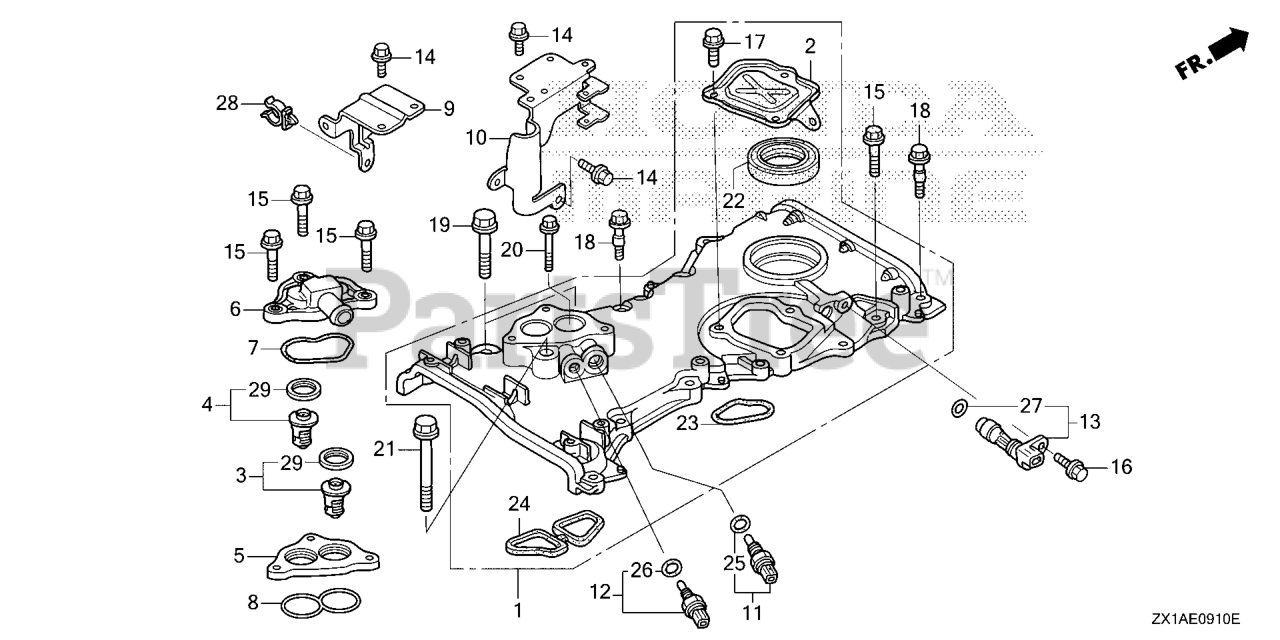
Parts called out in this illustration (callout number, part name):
1	CASE ASSY., CHAIN *NH8* (DARK GRAY)
1	CASE, CHAIN *NH8*
2	COVER, CHAIN CASE
3	THERMOSTAT ASSY.
4	THERMOSTAT ASSY.
5	SPACER KIT, THERMOSTAT COVER
5	SPACER, THERMOSTAT COVER
6	COVER, THERMOSTAT
7	GASKET, THERMOSTAT COVER
8	GASKET, THERMOSTAT SPACER (NOT AVAILABLE)
8	GASKET, THERMOSTAT SPACER
9	BRACKET B, HARNESS CLIP
10	BRACKET C, HARNESS CLIP
11	SENSOR ASSY., WATER TEMPERATURE
12	SENSOR ASSY., WATER TEMPERATURE
13	SENSOR ASSY., CRANK
14	BOLT, FLANGE (6X14) (CT200)
15	BOLT, FLANGE (6X28)
16	BOLT, FLANGE (6X16)
17	BOLT, FLANGE (6X14)
18	BOLT, SPECIAL (6X31)
19	BOLT, FLANGE (10X43)
20	BOLT, FLANGE (6X38)
21	BOLT, FLANGE (10X70)
22	OIL SEAL (43X58X7) (ARAI)
23	O-RING, CHAIN CASE
24	GASKET, CHAIN CASE
25	O-RING (9.5X1.5) (HONDA KIKAKI)
26	O-RING (9.5X1.9)
27	O-RING (15X1.9)
28	CLAMP (18.5MM)
29	RUBBER, RING
30	CASE KIT, CHAIN
31	SUB-WIRE HARNESS ASSY. (A)
32	SUB-WIRE HARNESS ASSY. (B)
33	BRACKET, SUB-HARNESS CLIP
34	BAND, WIRE HARNESS
35	CLIP, HARNESS BAND (145MM) (BLACK)
